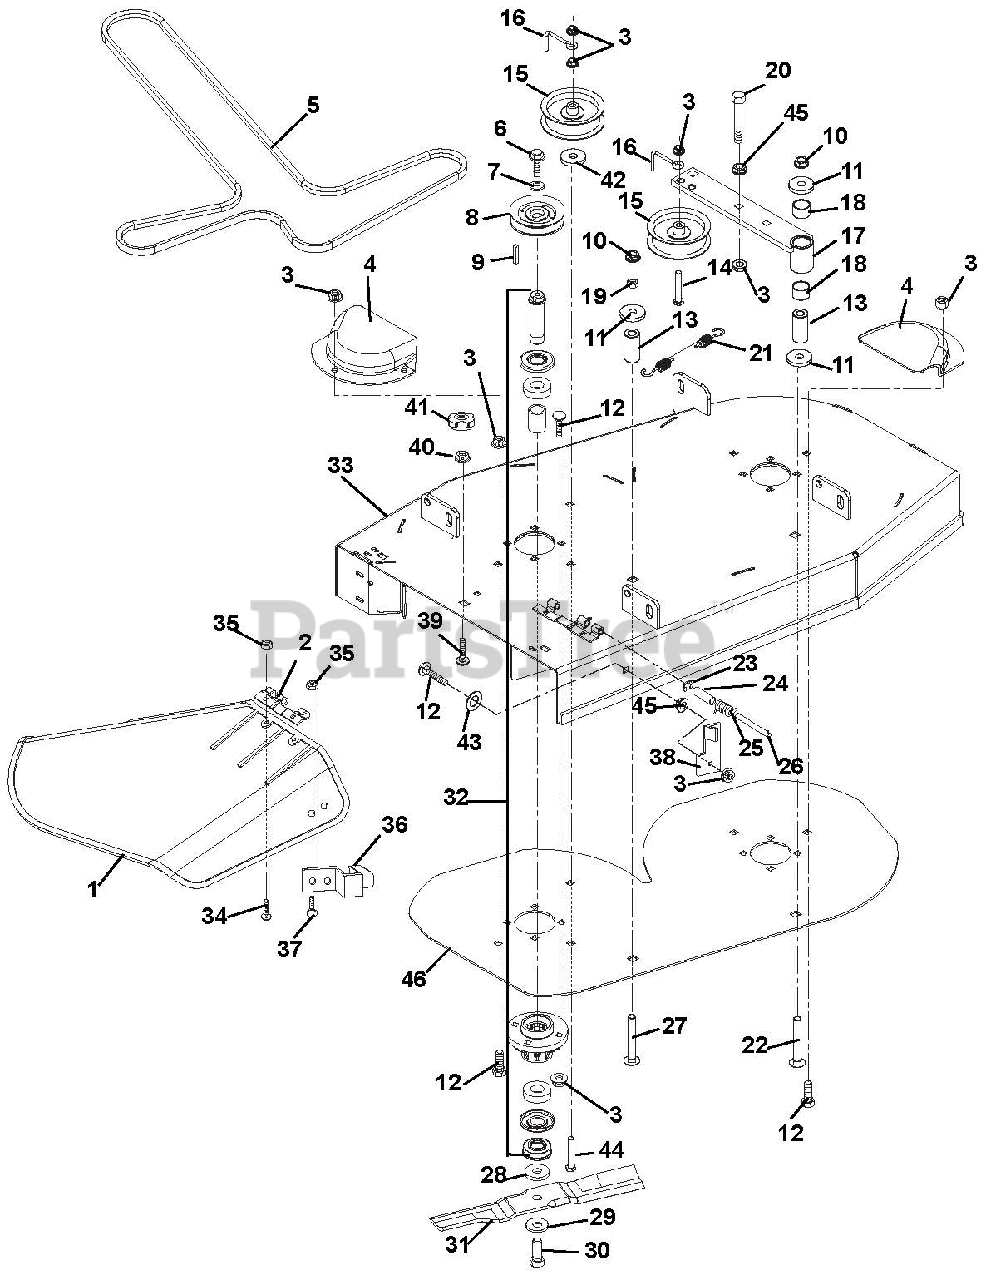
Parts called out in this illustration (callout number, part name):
1	Discharge Chute
2	Hinge, Plate
3	Nut, 3/8-16 Flange Nyloc
4	Belt Cover
5	V-Belt, HA x 97
6	Bolt, Hex .38-16 x 1.00 Grade 8 w/Epoxy Patch
7	Washer, Flat Steel .406 x 1.50 x .245
9	Key, Square .25 x .38 x .25
10	Nut, Locking Top Flange .50-13
11	Washer, Flat Steel .515 x .625 x .250
12	Bolt, Round Head Square Neck .38-16 x 1.25
14	Bolt, Hex .38-16 x 2.50
15	Idler Flanged 3.50
16	Finger Belt
17	Weldment, Idler Arm
18	Bearing, 1.00 x 1.12 x .75
19	Nut, Spinlock Flange .50-13
20	Bolt, Hex .38-16 x 2.00
21	Spring, Tension .187 x 1.50 x 9.94
22	Bolt, Round Head Square Neck .50-13 x 3.50
23	Ring, Retaining External .312 x .025
24	Bushing, Sleeve
25	Spring, Torsion .095 x .50 x 1.00
27	Bolt, Round Head Square Neck .50-13 x 3.75
28	Washer, Flat .688 x 1.75 x .134
29	Washer, Beveled .63 x 1.625 x .140
30	Bolt, Hex .62-18 x 1.75 Grade 8
31	Blade, Mower
32	Assembly, Spindle
33	34" Zoom/ZT Deck
34	Bolt, Round Head Square Neck .25-20 x .75 Grade 5
35	Nut, Locking Top Flange .25-20
36	Flat Spring
37	Bolt, Round Head Square Neck .25-20 x .50 Grade 5
38	Bracket, Chute Lock
39	Bolt, Round Head Square Neck .31-18 x 1.00
40	Nut, Spinlock Flange .312-18
41	Knob, Clamping
42	Spacer, .39 x 1.50 x .380
43	Washer, Flat Steel .563 x 1.38 x .109
44	Bolt, Round Head Square Neck .38-18 x 2.75 Grade 5
45	Nut, Spinlock Flange .375-16
46	Plate, 34" Doubler
